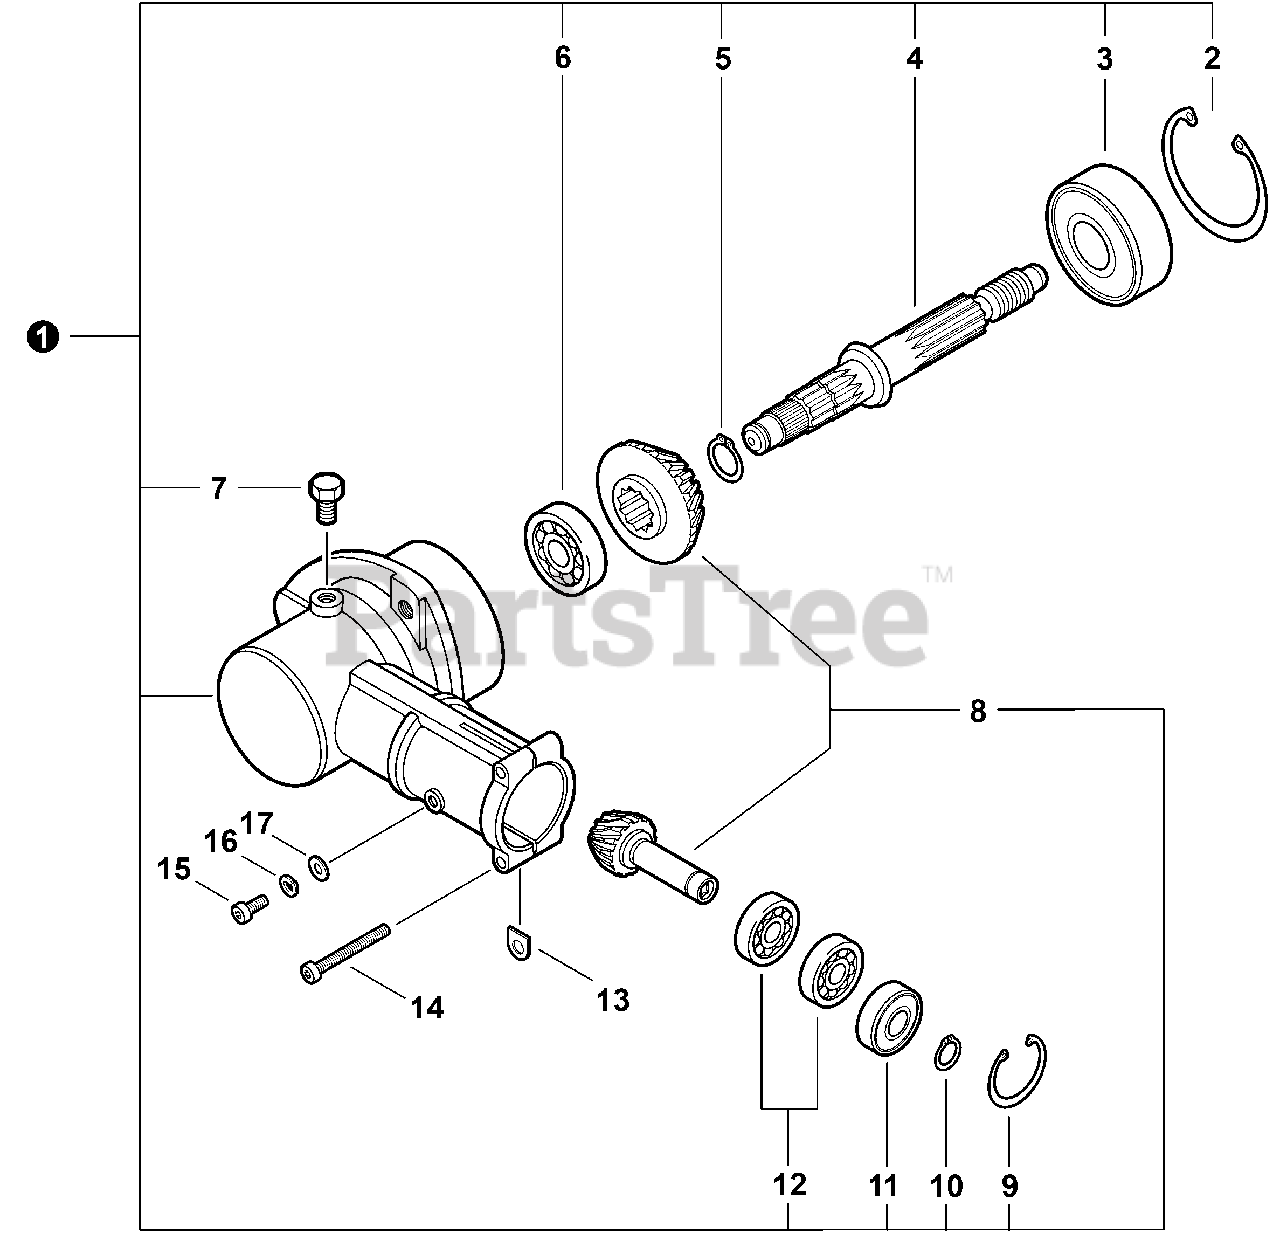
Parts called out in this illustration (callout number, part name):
1	GEAR CASE ASSY
2	RING, SNAP Ø42
3	BEARING, BALL 6302
4	SHAFT, GEAR
5	RING, SNAP Ø12
6	BEARING, BALL 629
7	BOLT M8×8
8	GEAR SET
9	RING, SNAP Ø22
10	RING, SNAP Ø10
11	BEARING, BALL 6900Z
12	BEARING, BALL 6900
14	BOLT, TORX 5×25
15	BOLT, TORX 5×12
16	WASHER, SPRING 5
17	WASHER, FLAT 5.5×10×0.8
